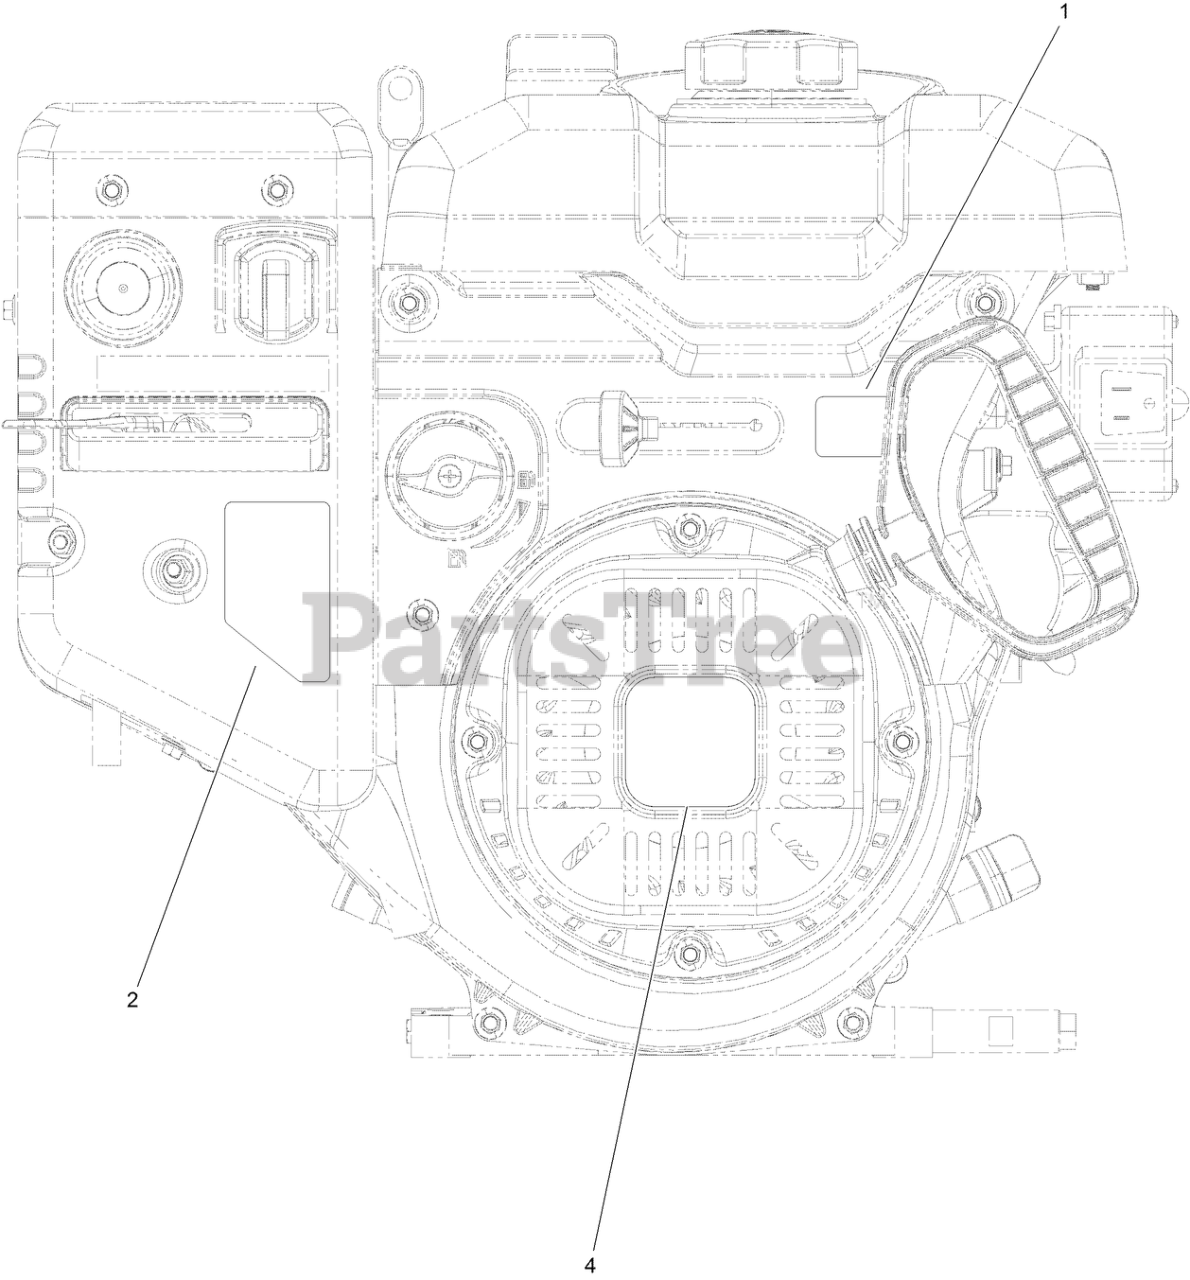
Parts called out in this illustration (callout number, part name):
1	DECAL-THROTTLE
2	DECAL-CONTROL, ENGINE
4	DECAL-RECOIL
